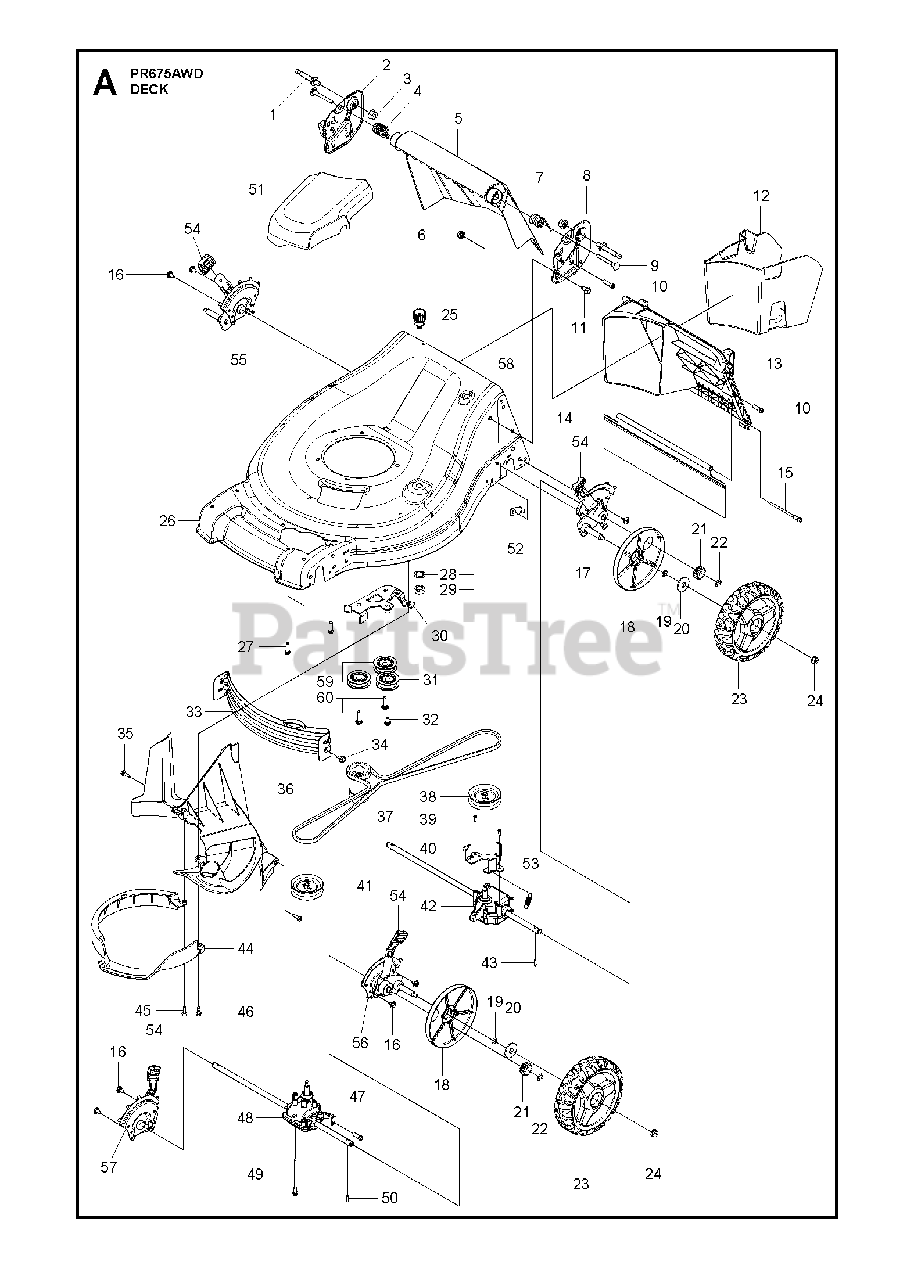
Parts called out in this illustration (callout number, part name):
1	Hand Pivot Bolt, 3125-18.21Eff
2	BRACKET.HANDLE.ADJ.21EFF.RH479
3	Flange Nut, Serrat.3125-18.5625
4	SPRING.RH.DOOR.21 EFF
5	DOOR.REAR.21 EFF.BLACK
6	Flange Nut, 3/8-16 Zinc
7	SPRING.LH.DOOR.21 EFF
8	BRACKET.HANDLE.ADJ.21EFF.LH479
9	Pivot Door Bolt, .375-16 21Eff
10	Screw, Hi-Lo,5/16-14 X T-45
11	BOLT.5/16HEX.WHS.HD
12	Mulch Plug, 21 Eff
13	Insert, Rear 21 Eff
14	Skirt, Rear 21" Eff
15	Screw, Hi-Lo.5/16-14 X 4.10
16	SCREW
17	Adjuster, 4Pt 21Eff Rf/Lr Blk
18	COVER.DUST.WHEEL.INNER.WALK
19	O-RING..070X.487.NEOPRENE
20	WASHER FLUT
21	PINIION.14.TOOTH.RGD
22	E-RING 7/16 RE
23	Wheel, 8 X 2 5 Spoke CAWD Yellow 421
24	NUT.HEX.FLANGE.3/8-16.LOCKNUT
25	FITTING, HOSE, WATER WASHOUT
26	KIT.HSG.21AWD.EFF.WO.428.CE SY
27	SCREW.HI-LO. 5/16 X 1.00
28	WASHER.LOCK.INTERNAL.TOOTH
29	LOCKNUT.HEX.WITH.O-RING
30	Idler Bracket Assembly, AWD
31	Idler Pulley, RWD Double Seal
32	SCREW
33	Front Baffle, 21" Eff
34	BOLT.5/16HEX.WHS.HD
35	Screw, Hi-Lo.13-16 X .750.375 X drv
36	Baffle Cover, 21 Eff
37	Drive Belt, 22EFF AWD
38	Drive Pulley, Sm Awd/Rwd
39	SCREW
40	BRACKET.TRAN.BELTKEEPER.22+RGD
41	Drive Pulley, Sm Awd/Rwd
42	Transmission, Awd Rear 21Eff
43	PAWL, DRIVE
44	Stripper Ring, 21 Eff
45	Screw, Hi-Lo.13-16 X .750.375 X drv
46	Shoulder Bolt, 1/4-20 Trilob
47	SCREW.HI-LO. 5/16 X 1.00
48	RB TRANSMISSION.AWD.FRONT.21EF
49	Screw, Hi-Lo.5/16-14 X 4.10
50	PAWL, DRIVE
51	Drive Cover, Full Husq 21Eff Awd
52	STRAP.PLATE ATTACH.21 EFF.GLV
53	SPRING.RETURN.AUTO.
54	SELECTOR KNOB
55	Adjuster, 4Pt 21Eff Lf/Rr Blk
56	Adjuster, 4Pt 21Eff Lf/Rr Blk
57	Adjuster, 4Pt 21Eff Rf/Lr Blk
58	KIT.WASH-OUT.PORT
59	Idler Pulley Assembly, 22+ AWD
